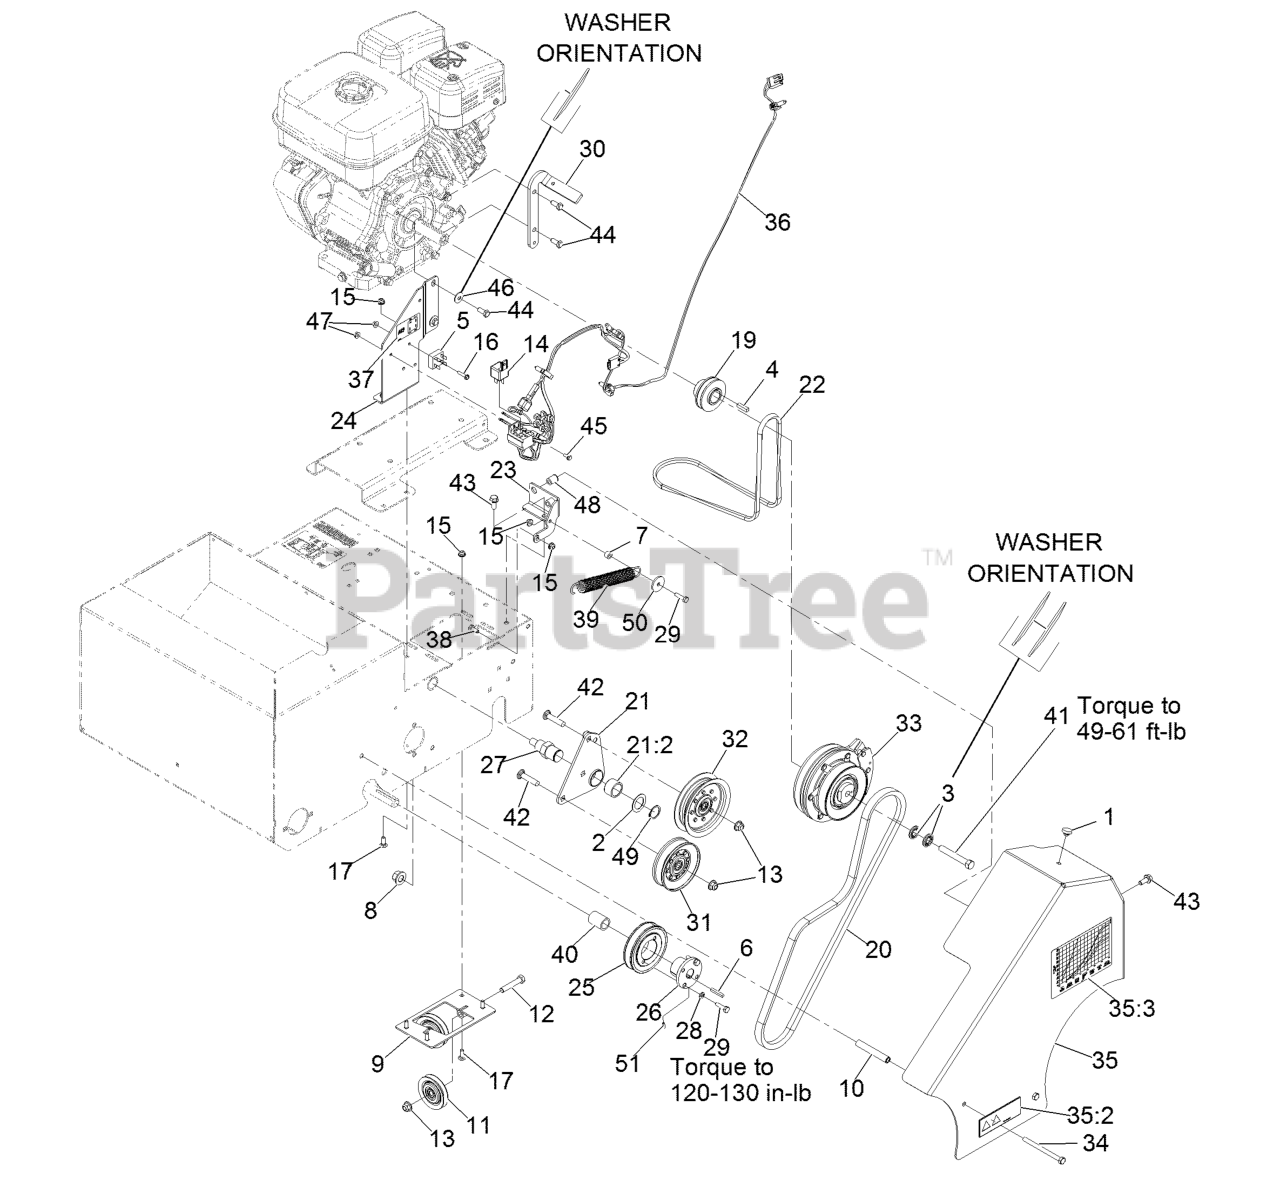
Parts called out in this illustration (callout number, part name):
2	Washer-Spacer
3	Washer-Spring Disc 7/16
4	Key-Machine 1/4 X 1/4 X 1
5	Rectifier-Bridge
6	Key-Machine 3/16 X 3/16 X 1 1/4
8	Nut-Lock 1/2-13
9	Pulley-Tension
10	Spacer-Kickstand, Long
11	Pulley-Idler
12	Screw-HH 3/8-16 X 2
13	Nut-Nyloc 3/8-16 Flg
15	Nut-Nyloc 1/4-20 Flg
16	Screw-HWH
17	Bolt-Carriage 1/4-20 X 3/4
19	Pulley-Mule Drive
20	Belt-Seeder, Clutch
21	Idler Arm ASM
21:2	Bushing
22	Belt-Mule Drive
23	Bracket-Spring
24	Support-Engine
25	Sheave-Taper Lock
26	Bushing-Taper Lock
27	Pivot-Idler
28	Washer-Lock 1/4
29	Screw-HH 1/4-20 X 1
30	Stop-Clutch
31	Pulley-Idler V
32	Pulley-Idler Flat (4.06-Inch)
33	Clutch-Electric
34	Screw-HH 5/16-18 X 4
35	Belt Guard ASM
35:2	Decal-Danger
35:3	Decal-Seed Graph
36	Harness-Slicer/Seeder
37	Decal-Bridge Rectifier
38	Screw-HH 1/4-20 X 5/8
39	Spring-Extension
41	Screw-HH 7/16-20 X 3
42	Bolt-Carriage 3/8-16 X 1 3/4
43	Screw-HH Flg 5/16-18 X 3/4
44	Screw-HH 5/16-24 X 3/4
45	Screw-HWH
46	Washer-Spring Disc
47	Nut-Flange #10-24 Top Lock
48	Nut-Insert
49	Ring-Retaining
50	Washer
51	Screw-Set, Hs
